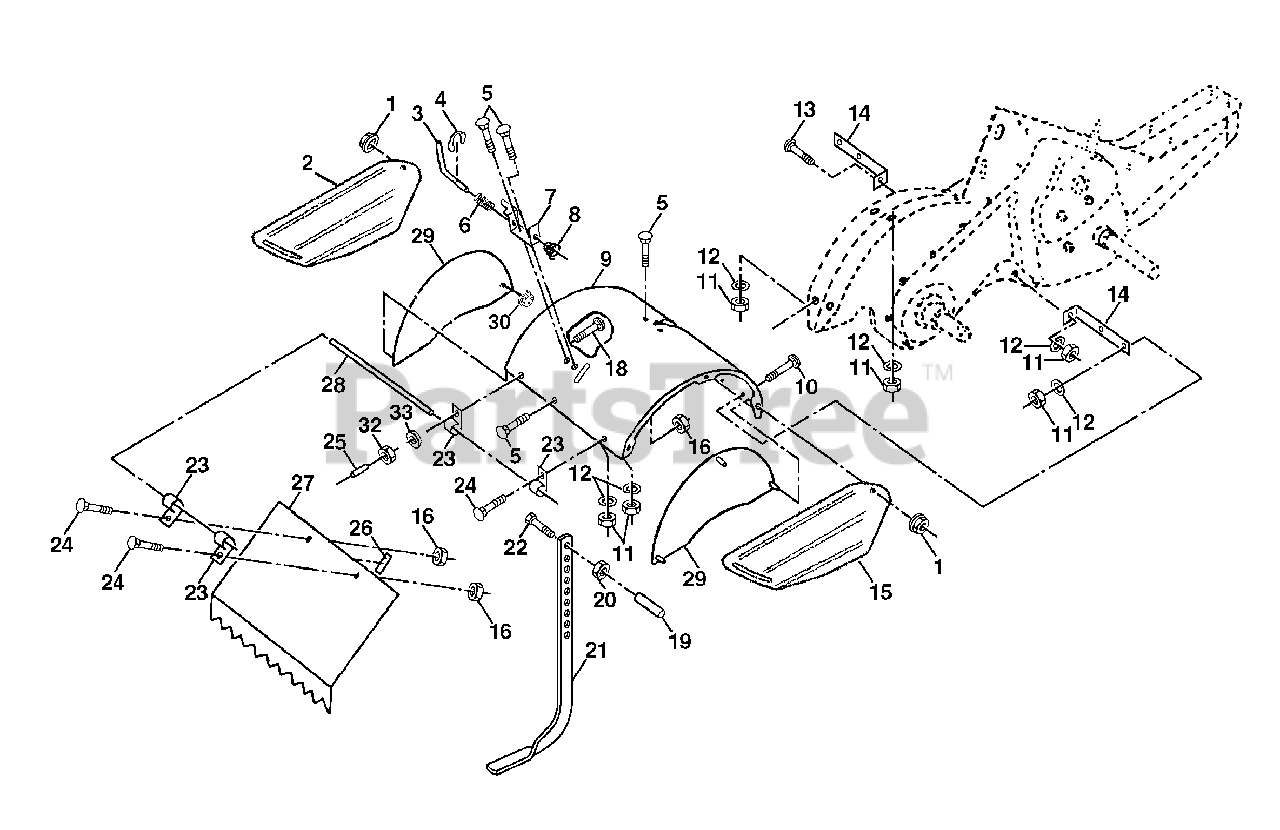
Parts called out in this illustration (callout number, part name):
1	Nut, Flange 5/16-18
2	Shield, Side, Outer L. H.
3	Pin, Stake, Depth
4	Ring, Klip
5	Bolt, Carriage 5/16-18 x 3/4 Gr. 5
6	Spring
7	Bracket, Latch
8	Spring, Depth Stake
9	Shield, Tine
10	Bolt, Carriage 5/16-18 UNC x 1
11	Nut, Hex 5/16-18
12	Washer, Lock 5/16
13	Bolt, Carriage 5/16-18 x 1-1/4
14	Bracket, Shield Tine
15	Shield, Side, Outer R.H.
16	Nut, Hex Flange 1/4-20 UNC
18	Bolt, Carriage 1/4-20 x 1-1/4 Gr. 5
19	Grip
20	Nut, Hex 3/8-16
21	Stake, Depth
22	Bolt, Hex 3/8-16 x 2
23	Hinge
24	Bolt, Carriage 1/4-20 x 1/2 Gr. 5
25	Cap, Vinyl
26	Pad, Idler
27	Shield, Leveling
28	Pin, Hinge
29	Shield, Side
30	Locknut, Flange 5/16-18
32	Nut Fin Hex 1/4-20 UNC
33	Washer Lock Hvy Helical 1/4
